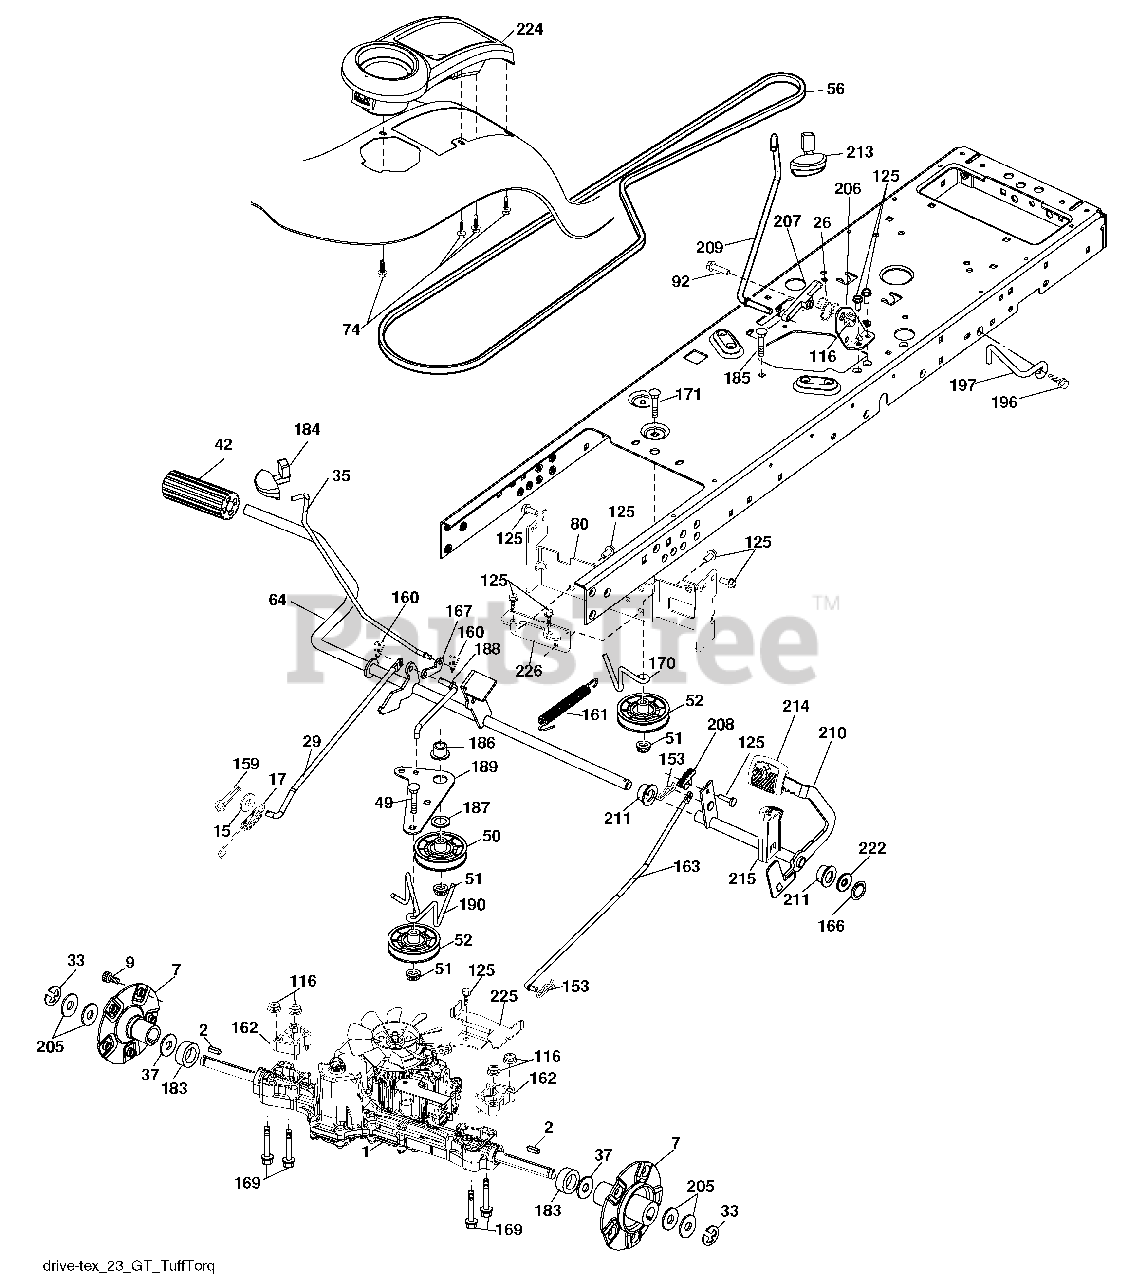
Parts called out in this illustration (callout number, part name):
2	Key
7	Hub Asm. Wheel
9	Bolt Hub Wheel
15	Washer 13/32 x 13/16 x 16 Ga.
17	Spring, Brake
26	Spring Return Cruise
29	Rod, Brake
33	Ring E
35	Rod, Brake, Park
37	Washer
42	Cover, Foot Pedal
49	Bolt
50	Pulley Idler Flat
51	Lock Nut 3/8-16
52	Idler V-Groove 910" Offset
56	V-Belt, Drive
64	Shaft Asm. Pedal Brake Control
74	Screw Hx Wsh Hi-Lo 1/4 x 1/2 unc
80	Strap Torque
92	Bolt Fin Hex 5/16-18 unc x 1.25
116	Nut Lock Hex Flange 5/16-18
125	Screw 5/16-18 x 3/4
153	Retainer Spring
159	Pin Cotter 1/8 x 3/4
160	Retainer Clip
161	Spring, Return, Clutch
162	Spacer Transaxle
163	Rod Pedal Control
166	Nut Push .625
167	Latch Brake Parking
169	Bolt Hex Flghd 5/16-18 x 3.0 Gr. 5
169	Bolt 5/16-18 x 3.75
170	Keeper Belt Centerspan
171	Bolt
183	Spacer Split
184	Handle Parking Brake
185	Bolt
186	Spacer Retainer
187	Washer
188	Link Clutch Ground Drive
189	Bellcrank Ground Drive
190	Keeper Bellcrank Ground Drive
196	Screw 3/8-16 x 1
197	Bracket Clutch Anti-Rotation
205	Washer
206	Bracket Mount Latch Cruise
207	Latch Control Cruise
208	Bolt Sector Control Cruise
209	Rod Conrtrol Cruise
210	Rocker Asm. Pdeal Control
211	Bearing Nylon
213	Knob Control Cruise
214	Pad Pedal Forward
215	Pad Pedal Reverse
222	Washer 21/32 x 1-1/4 x 10 Ga.
224	Console Toolbox
225	Keeper Belt Trans.
226	Bracket Mount Torque
